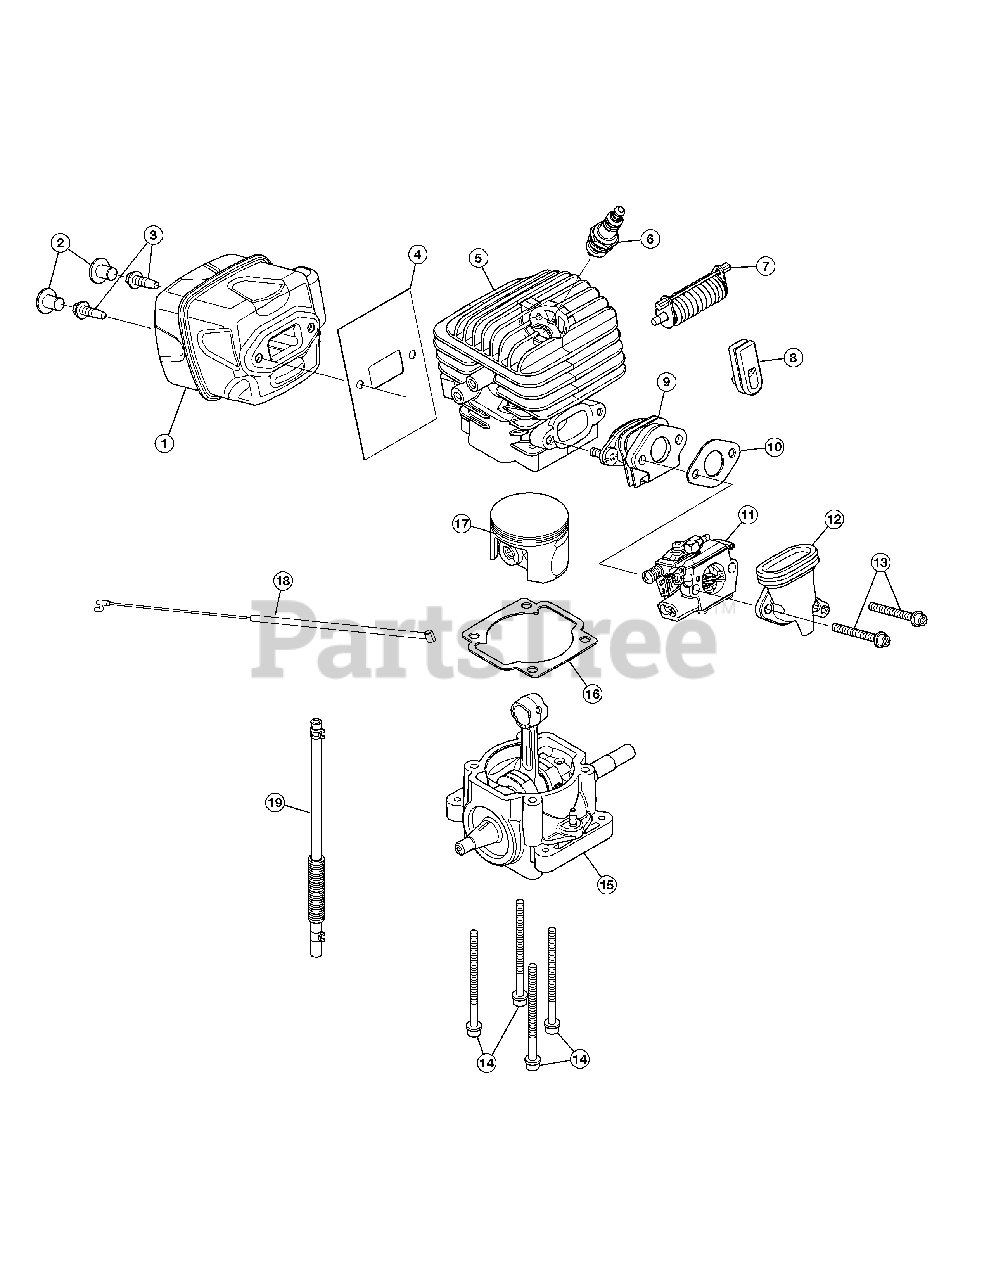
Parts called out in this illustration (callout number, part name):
1	Muffler Assembly (Incl. 2, 3 & 4)
2	Muffler Plug
3	Muffler Screw
4	Muffler Gasket
5	Cylinder Assembly (Incl. 6, 8 & 10)
6	Spark Plug
7	Isolator Assembly
8	Grommet
9	Insulator Assembly
10	Carburetor Gasket
11	Carburetor
12	Boot & Bracket Assembly (Incl. 8 & 18)
13	Carburetor Hardware
14	Cylinder Hardware
15	Shortblock Assembly (Incl. 4 - 10)
16	Cylinder Gasket
17	Piston Assembly
18	Throttle Cable
19	Breather Hose (with Clamp)
